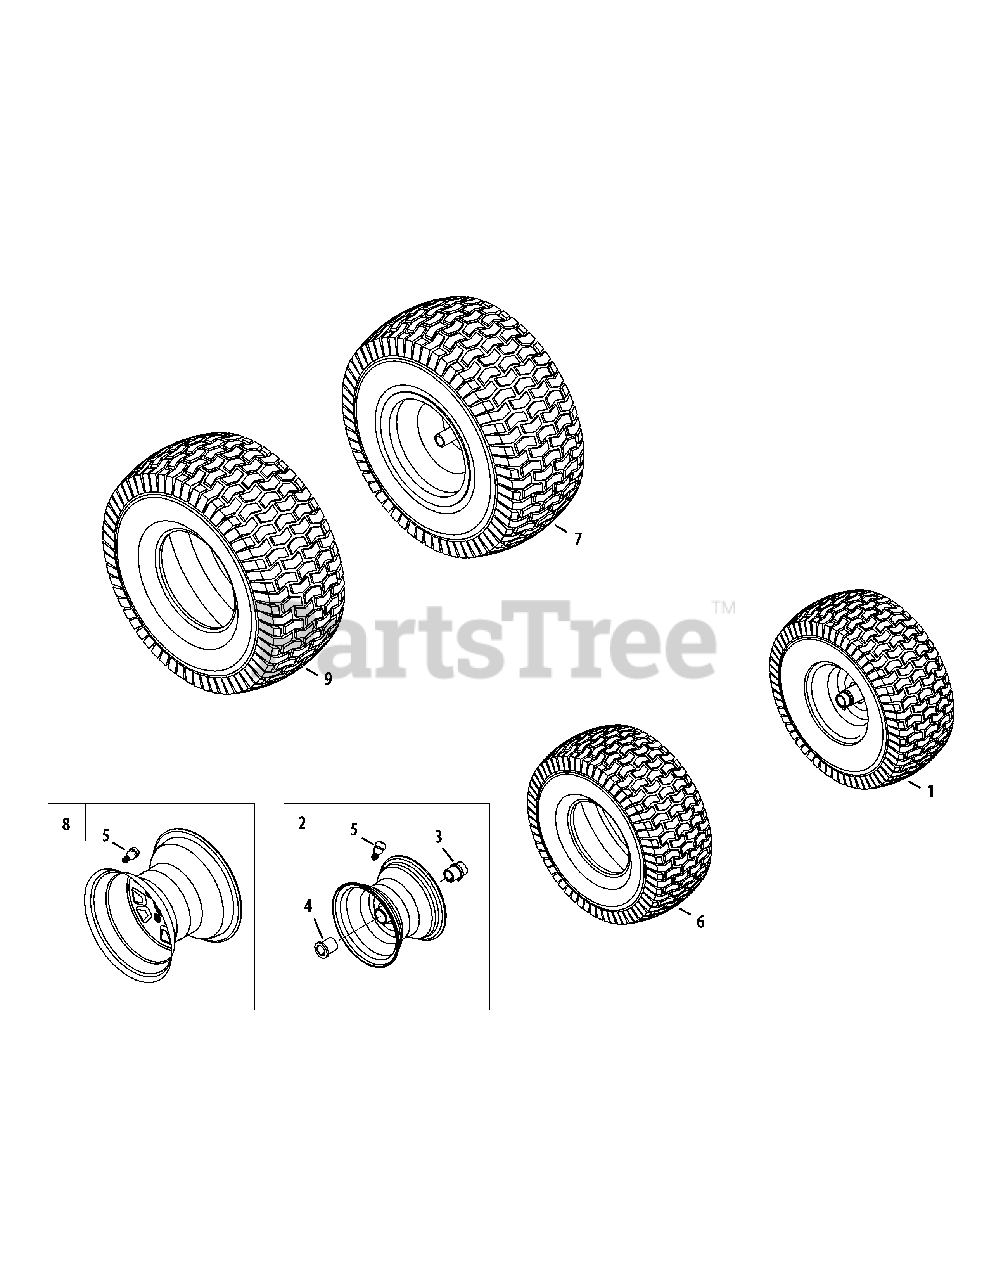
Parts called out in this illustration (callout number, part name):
1	Wheel Ass’y, Complete, 16 x 6 x 5.8
2	Rim Ass’y, 8.0 x 5.3, Flange Bearings
3	Bearing, Flange, .760 ID w/ Fitting
4	Bearing, Flange, .760 x 1.00 x 1.20
5	Valve, Tubeless Air
6	Tire, 15 x 6.5 x 8 Sq Shoulder
7	Wheel, Complete, 22 x 9.5 x 12
8	Rim Ass’y, 12.0 x 7.0
9	Tire, 22 x 9.5 x 12 Sq Shoulder
